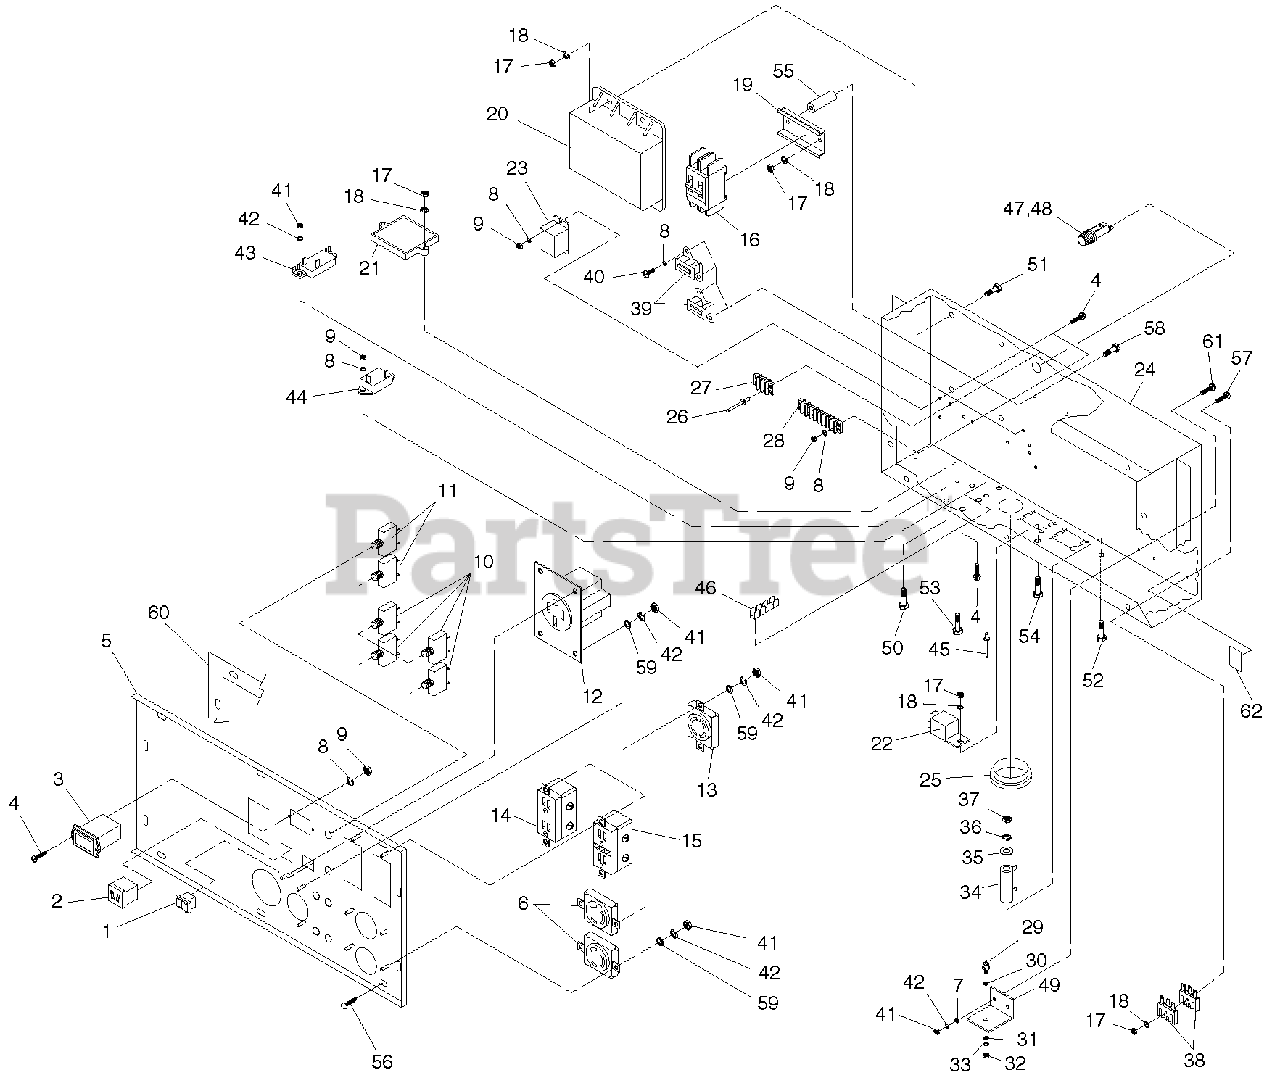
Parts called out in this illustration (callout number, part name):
1	SWITCH, ROCKER -/0
2	OUTLET, 12VDC SNAP
3	HOURMETER
4	SCREW PPHM M3-0.5 X 12
5	PANEL, SHEET METAL
6	OUTLET 30A 120V RECEPT
7	WASHER FLAT #6
8	WASHER LOCK M3
9	NUT HEX M3-0.5 G8
10	CIRCUIT BREAKER 30A
11	CIRCUIT BREAKER 20A
12	OUTLET 50A 125/250V
13	OUTLET 30A 125/250V
14	OUTLET 20A 120V DPLX
15	OUTLET 20A 120V GFCI
16	CIRCUIT BREAKER 50A 400V 2POLE
17	NUT HEX M5-0.8 G8
18	WASHER LOCK #10
19	DIN RAIL 59.5mm LONG
20	ASSEMBLY VOLTAGE REGULATOR 60HZ
21	ELECTRONIC GOVERNOR / IDLE CONTROLLER
22	RELAY PNL 12VDC SPST 30A
23	RELAY 12VDC 5A 3PDT 240V
24	CONTROL PANEL BOX
25	BUSHING SNAP
26	RIVET POP .156 X .160-.164 / #20
27	BLOCK TERMINAL 20A 2 X 6 X 1100V
28	BLOCK DOUBLE ROW TERMINAL 8 POSITION
29	RECTIFIER MSC 12A 600V
30	WASHER MICA .203
31	WASHER STEP NYLON .20
32	NUT HEX #10-32
33	WASHER FLAT #10
34	RESISTOR 25R 5% 25W
35	WASHER FLAT 1/4
36	WASHER LOCK M6-1/4
37	NUT HEX M6-1.0 G8
38	RECTIFIER-BATTERY CHARGER
39	TRANSFORMER, IDLE CURRENT
40	SCREW PPHM M3-0.5 X 8
41	NUT HEX M4-0.7 G8
42	WASHER LOCK M4
43	CIRCUIT BREAKER 5 X 1
44	CIRCUIT BREAKER 10 X 1 12VDC 1/4"QC
45	RIVET POP .125 X .129-.133 / #30
46	LUG GRND 8 TABS
47	HOLDER FUSE
48	FUSE 10A X AGC10
49	HEATSINK
50	SCREW PPHM M4-0.7 X 10
51	SCREW HHC M5-0.8 X 16 G8.8
52	SCREW HHC M6-1.0 X 65 G8.8
53	SCREW HHC M5-0.8 X 25 G8.8
54	SCREW HHC M5-0.8 X 10 G8.8
55	SPACER .25 X .50 X 1.5
56	SCREW HHTT M5-0.8 X 10
57	SCREW PPHM M5-0.8 X 30
58	SCREW PPHM M5-0.8 X 50
59	WASHER FLAT #8
60	GASKET, PORTABLE CONTROL PANEL
61	SCREW PPHM M4-0.7 X 16
62	TAPE ELEC UL PERMACEL
